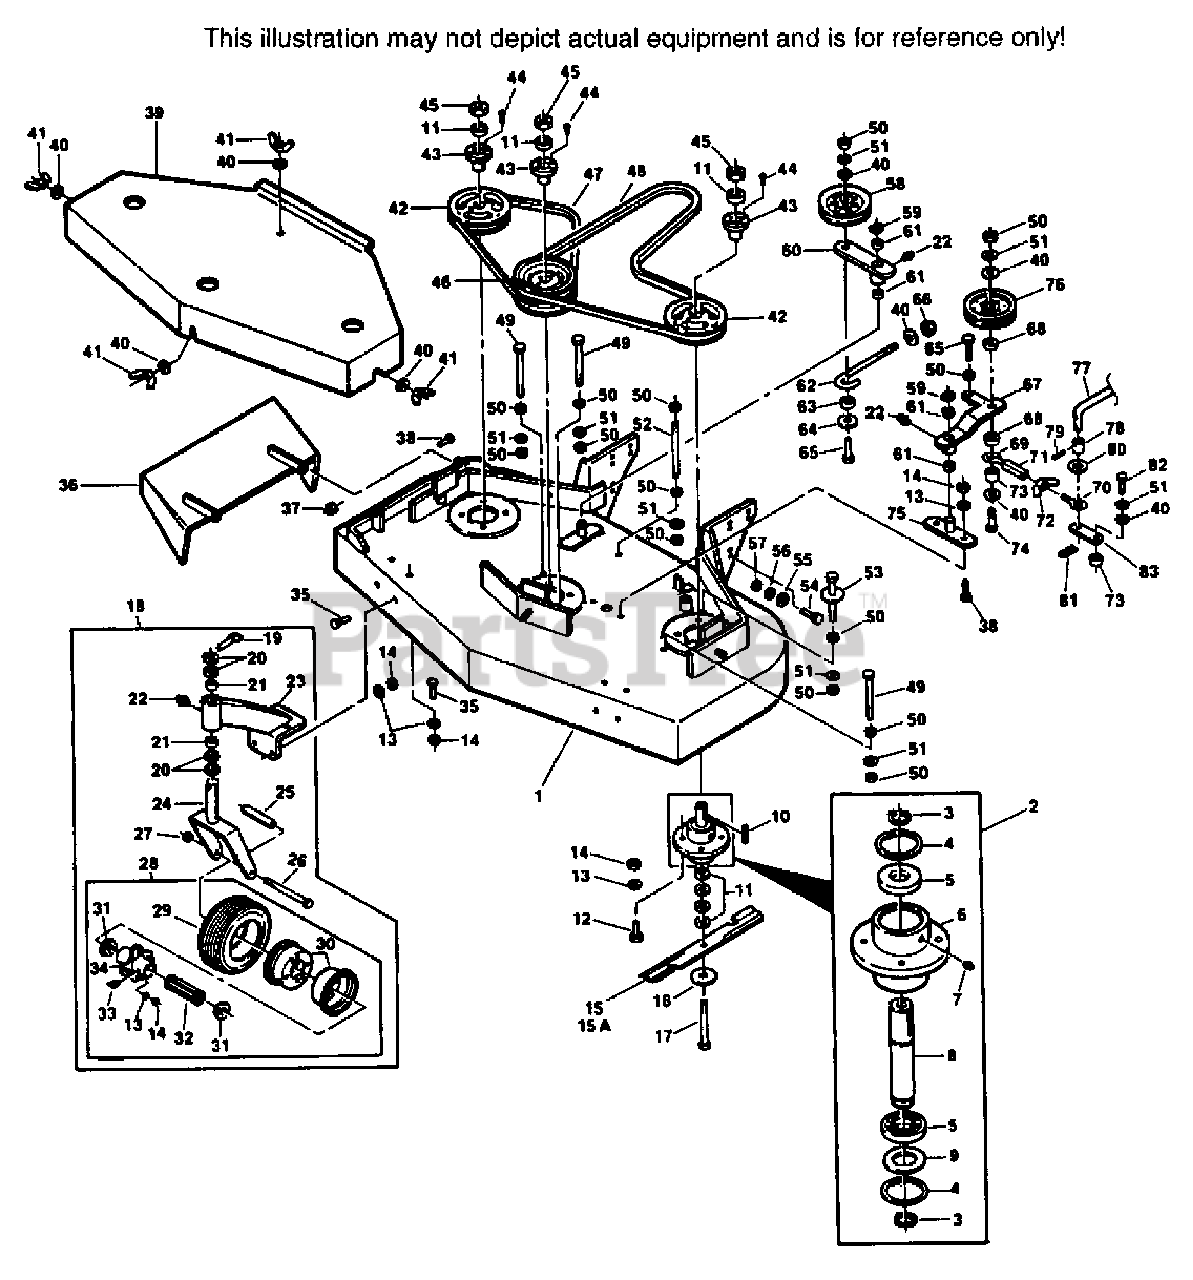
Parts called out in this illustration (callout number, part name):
1	CUTTER DECK(INCL. DECAL)
2	CUTTER SPINDLE ASSY.(INCL. 3-9)
3	RETAINING RING, 1" EXT.-INVERTED
4	RETAINING RING, 2-7/16" INT. BASIC
5	BEARING, CUTTER SPINDLE UPPER
5A	BEARING, CUTTER SPINDLE LOWER
6	SPINDLE HOUSING
7	GREASE FITTING STR. 5/16 SERR.
8	SPINDLE, CUTTER BLADE
9	WASHER, 1-5/16 X 2-13/32 X 16 GA
10	KEY, 1/4 X 1/4 X 2
11	SPACER, CUTTER BLADE
15	CUTTER BLADE 16-1/2"
15A	CUTTER BLADE 16-1/2" HI LIFT
16	FLAT WASHER, 5/8"W
17	HEX HD BOLT, 5/8-11 X 9-1/2"
18	CASTER ASSY, COMP.(INCL. 19-28)
19	QUICK PIN
20	SPACER, CASTER YOKE, 1/2" LONG
21	BRONZE BEARING
22	GREASE FITTING, STR., 1/4-28
23	SUPPORT ASSY.(INCL. 21-22)
24	CASTER YOKE WLD.
25	SLEEVE, CASTER WHEEL BEARING
26	HEX HD BOLT, 1/2-13 X 5-1/2"
28	WHEEL ASSY.(INCL. 13-14A, 29-34)
29	TIRE ONLY, CASTER WHEEL
30	RIM PAIR, CASTER WHEEL
31	RETAINER, BEARING, CASTER WHEEL
32	ROLLER BEARING, CASTER WHEEL
33	GREASE FITTING 45' 1/4-28
34	HUB ASSY, CASTER WHEEL
36	DISCHARGE CHUTE WLD
37	HEX NUT, 5/16-18 ELASTIC STOP
39	BELT COVER ASSY.(INCL. DECALS)
40	WASHER 25/64 X 15/16 X 12 GA.
41	WING NUT, 3/8-16
42	PULLEY(INCL. 43-44)
43	TAPERED HUB
46	PULLEY, DOUBLE(INCL. 43-44)
47	BELT, RH BLADE DRIVE
48	BELT, BLADE DRIVE
50A	HEX NUT 3/8-16, CENTERLOCK
52	SUPPORT, BELT COVER
53	BELT GUIDE WLD.
55	WASHER, 15/32 X 59/64 X 16 GA.
58	IDLER PULLEY, "V" GROOVE
59	RETAINING RING, 3/4" EXT."E"
60	IDLER ARM ASSY,(INCL. 22 & 66)
61	BRONZE BEARING
62	ROD, IDLER PULL, J
63	SPACER, J PULL ROD
64	WASHER, 3/8 X 1-1/2 X 16 GA.
66	HEX NUT, 3/8-16 ELASTIC STOP
67	IDLER ARM(INCL. 22 & 61)
68	SPACER
69	EYEBOLT, LH
70	EYEBOLT, RH
71	TURNBUCKLE
72	WING NUT, 5/16-18
73	SLEEVE, CAM CLUTCH
75	IDLER PIVOT WLD.
76	IDLER PULLEY, BELT CLUTCH
77	BLADE CLUTCH ROD, LOWER
78	SLEEVE, CLUTCH ROD
80	WASHER, 33/64 X 1 X 16 GA
81	HAIR PIN LARGE
83	CAM LINK
87	BELT GUIDE
